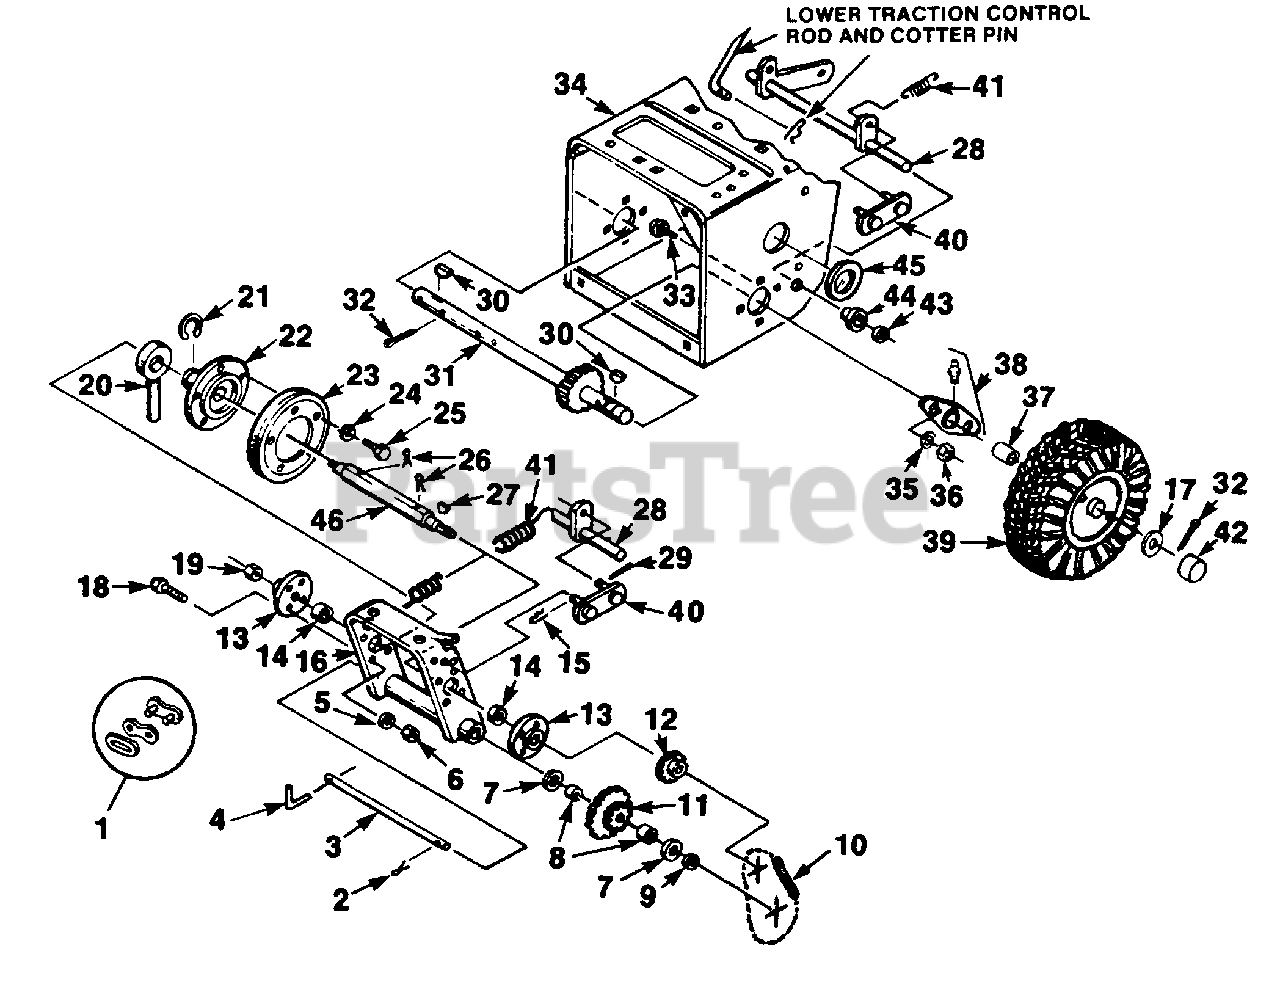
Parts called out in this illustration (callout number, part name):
1	LINK- Connecting (chain)
2	PIN- Cotter 3/16 x 1"
3	SHAFT- Disc bracket pivot
4	PIN- Anti-rotation
5	WASHER- Lock med. 1/4"
6	NUT- Hex 1/4-20
7	WASHER- Thrust
8	BEARING- Roller
10	CHAIN- Traction
11	PINION AND SPROCKET ASSEMBLY
13	RETAINER- Bearing
14	BEARING- DISC Shaft
15	PIN- Cotter
16	DISC BRACKET ASSEMBLY
17	WASHER- Wheel mounting
18	SCREW- Hex hd. cap 1/4-20 x 5/8"
19	NUT- Hex jam C/lock 1/2-13
20	SLEEVE & BEARING ASSY.
21	RING- Tru-Arc retaining
22	HUB- Drive disc
23	WHEEL- Drive
24	WASHER- Lock med. 5/16"
25	SCREW- Hex hd. cap 5/16-18 x 1/2"
26	PIN- Cotter 1/8 x 1"
27	KEY- Drive sprocket woodruff 1/8 x 1/2"
28	PIVOT ASSEMBLY
29	PIN- Cotter 3/32 x 3/4"
30	KEY- Morton 3/16 x 3/4"
31	AXLE & GEAR ASSEMBLY
32	PIN- Cotter 1/8 x 1 1/4"
33	BOLT- Shnk carr. 5/16-18 x 3/4"
34	FRAME ASSEMBLY
35	WASHER- Lock hvy. 5/16"
36	NUT- Hex 5/16-18
38	BEARING- Axle
39	WHEEL & TIRE (L.H.)
40	CLUTCH CONTROL LINK ASSEMBLY
41	SPRING- Clutch return
43	RETAINER TINNERMAN Pivot Shaft
44	BUSHING Pivot Shaft
45	PLUG- Tractor frame
46	SHAFT- Driving disc
